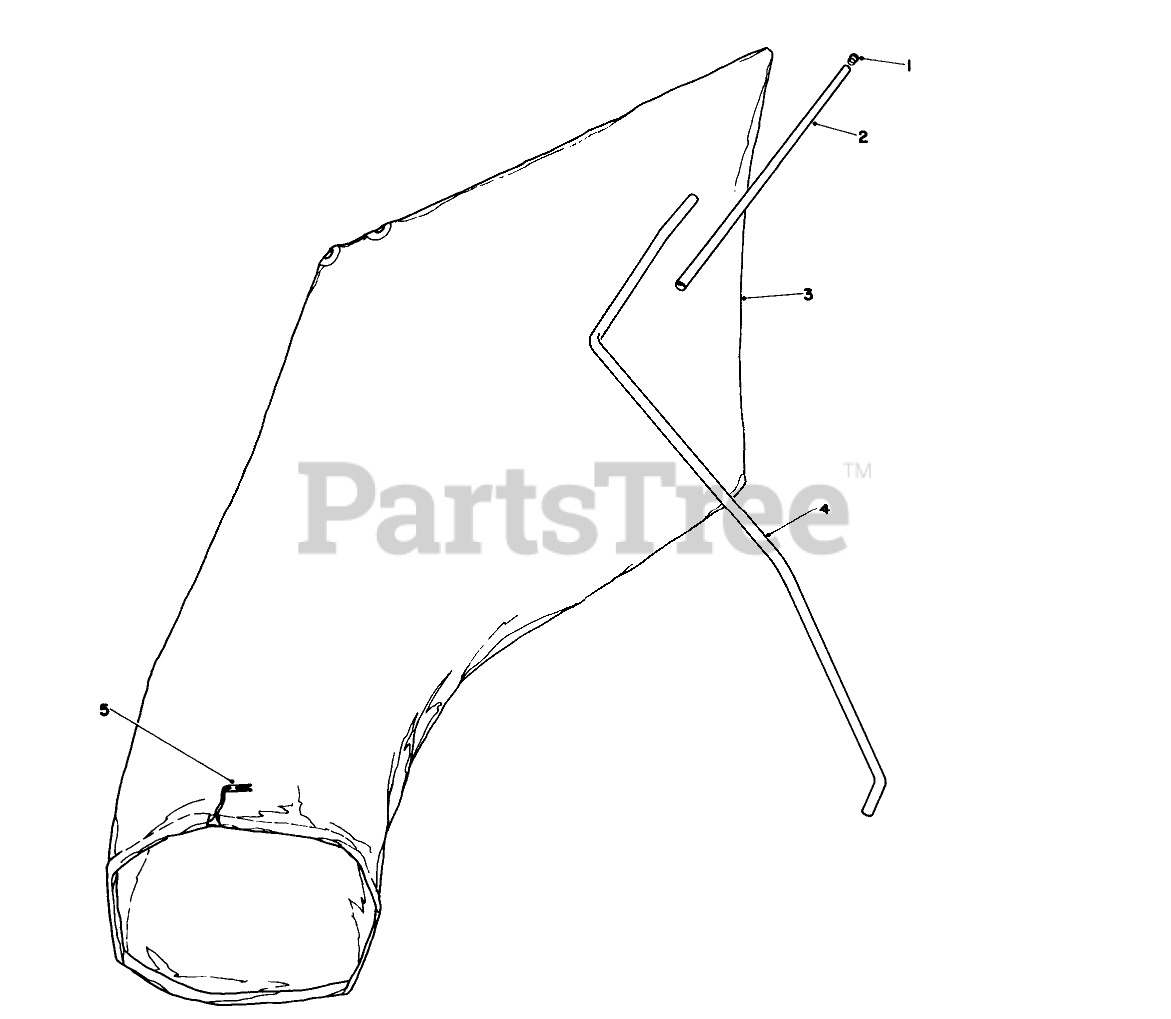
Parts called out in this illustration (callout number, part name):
2	BAG HANGER TUBE
3	Bag (Incl. Ref.#5)
4	HANGER ROD
5	BAG CORD FASTENER
